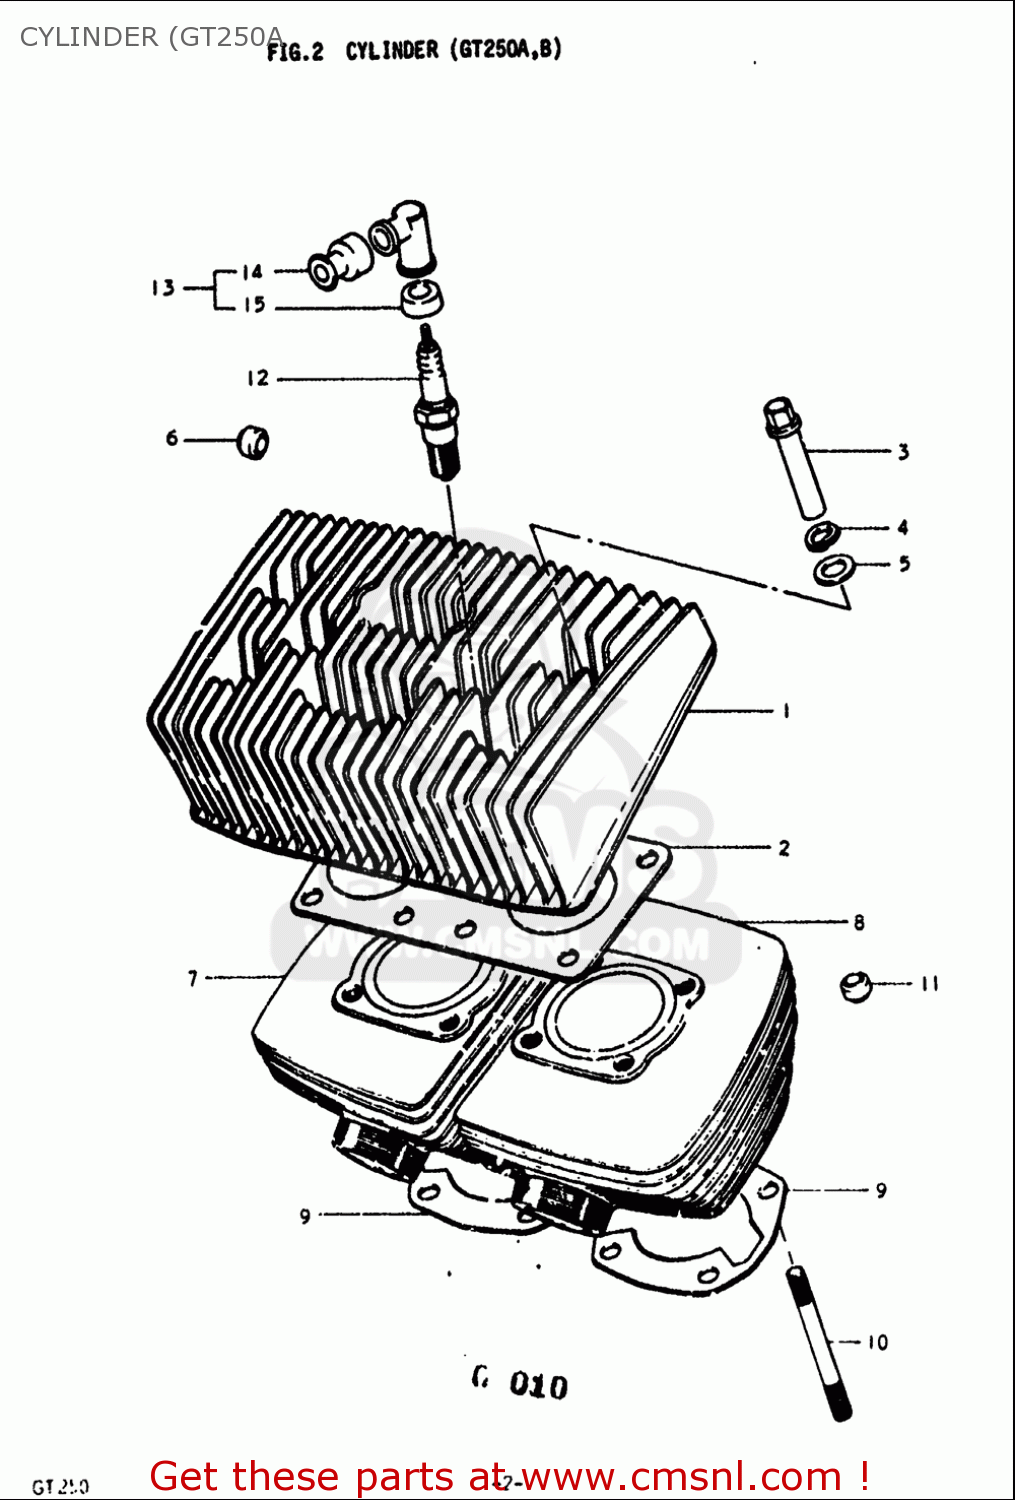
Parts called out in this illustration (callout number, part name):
2	GASKET,CYLINDER HEAD (NAS)
3	NUT (8MM)
4	WASHER,LOCK
5	WASHER
6	PAD,CYLINDER HEAD
9	GASKET,CYLINDER (NAS)
10	BOLT,STUD
11	PAD,CYLINDER HEAD
12	PLUG,SPARK
13	CAP,SPARK PLUG
14	SEAL,HIGH TENSION CORD
15	SEAL,SPARK PLUG
